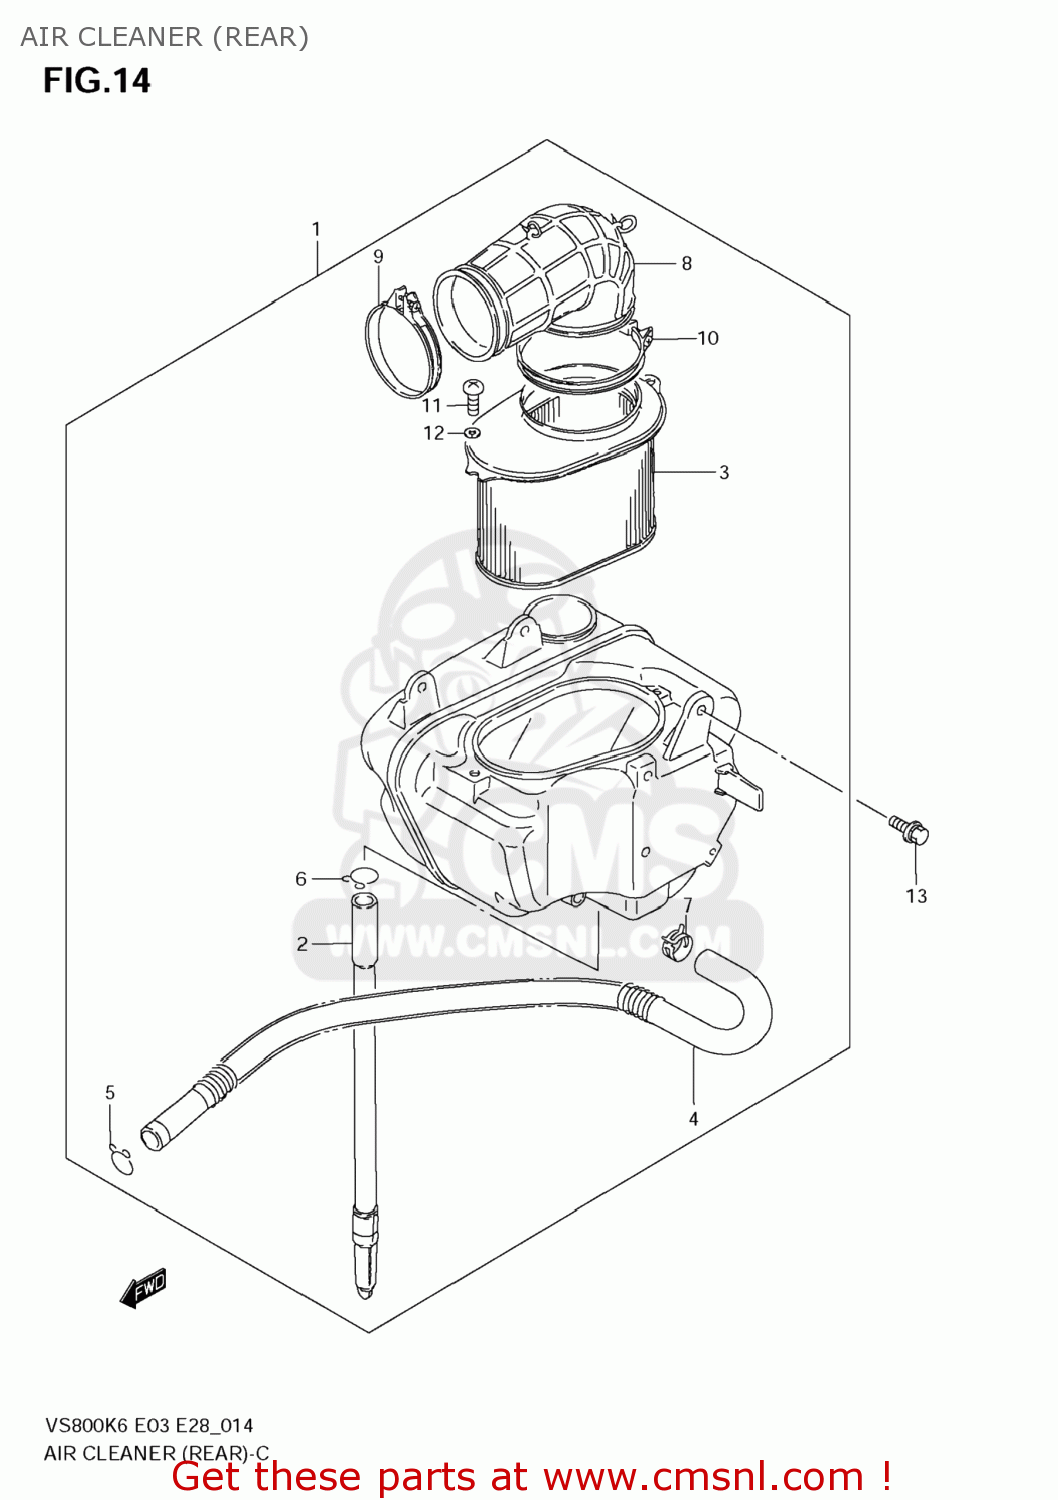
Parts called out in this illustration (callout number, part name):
1	CLEANER ASSY,AIR RR
2	TUBE,DRAIN
3	FILTER ASSY
4	TUBE SET,BREATHER
5	CLIP
6	CLIP
7	CLIP
8	TUBE,AIR CLEANER OUTLET
9	CLAMP
10	CLAMP
11	SCREW
12	LOCK,WASHER
13	BOLT
